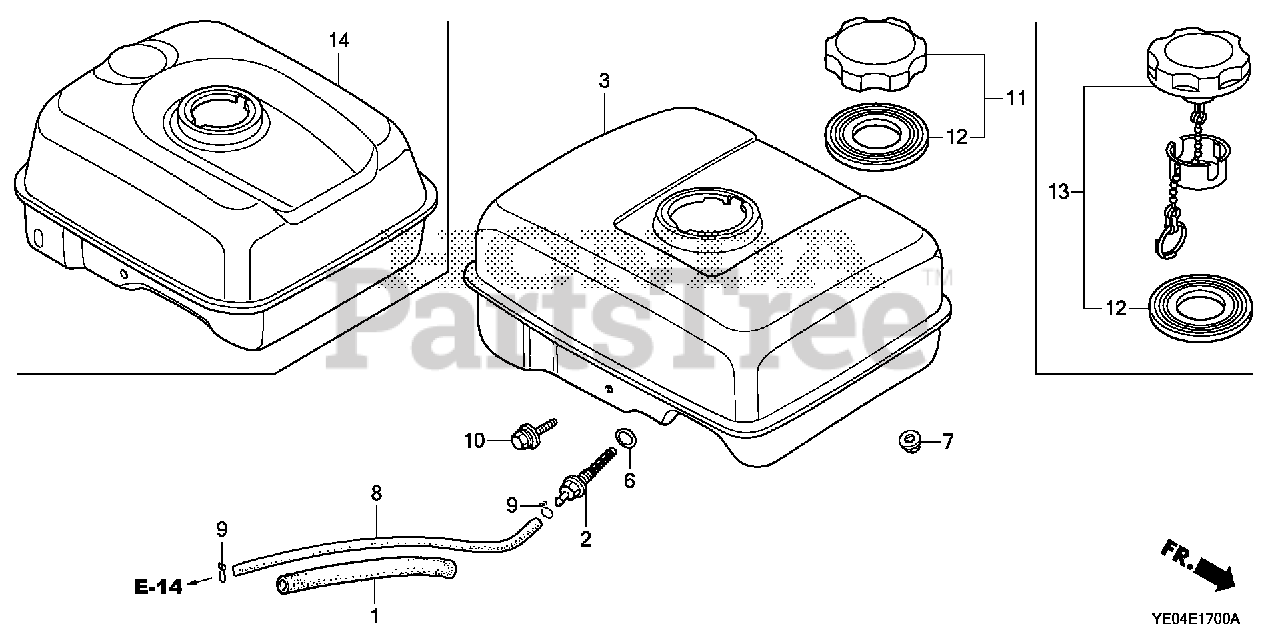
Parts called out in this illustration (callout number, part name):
1	RUBBER, SUPPORTER (107MM)
2	JOINT, FUEL TANK
3	TANK, FUEL *NH31* (MCKINLEY WHITE) Use up to Engine SN 3033315.
6	O-RING (14MM) (ARAI) Use up to Engine SN 2949254.
6	O-RING (14MM) (NOK)
7	NUT, FLANGE (6MM)
8	TUBE, FUEL (4.5X145) (FKM)
9	CLIP, TUBE (D8)
10	BOLT, FLANGE (6X29)
12	GASKET, FUEL FILLER CAP
12	GASKET, FUEL FILLER CAP (39X62X3) (TOUYOUSYA)
13	CAP, FUEL FILLER
